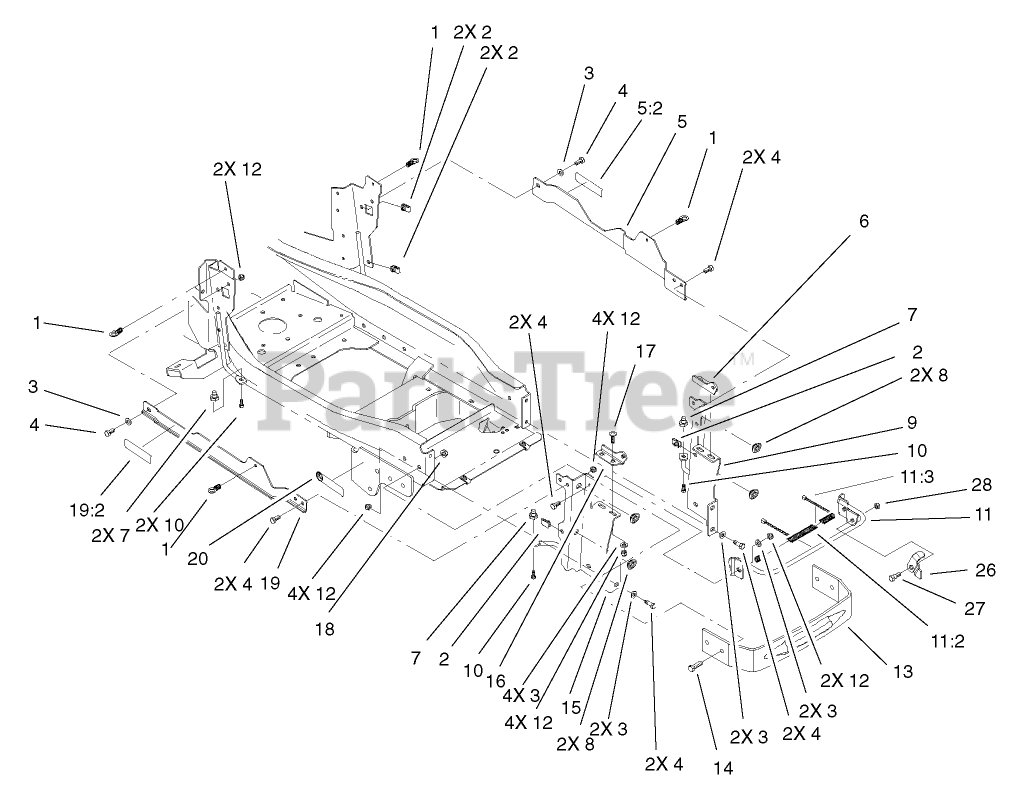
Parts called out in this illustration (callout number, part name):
1	LATCH ASM
3	WASHER-PLAIN
4	SCREW-HH
5	SUPPORT / DECAL ASM
5:2	DECAL-WARNING
6	BRACKET-HINGE, LOWER LH
7	MOUNT-SIDEPANEL
8	GROMMET
10	SCREW-PLASTITE
11:2	COVER-BRACE
11:3	TIE-CABLE
12	NUT-LOCK, NI
14	SCREW-HH
15	SUPPORT-HOOD, RH
16	BRACKET-HINGE, LOWER RH
17	SCREW-CARR
18	NUT-LOCK, NI
19	SUPPORT ASM
19:2	DECAL-WARNING
20	DECAL-ATTACH A-MATIC
26	LEVER-PROP, HOOD
27	BOLT-SHOULDER,HFH
28	NUT-LOCK, NI
